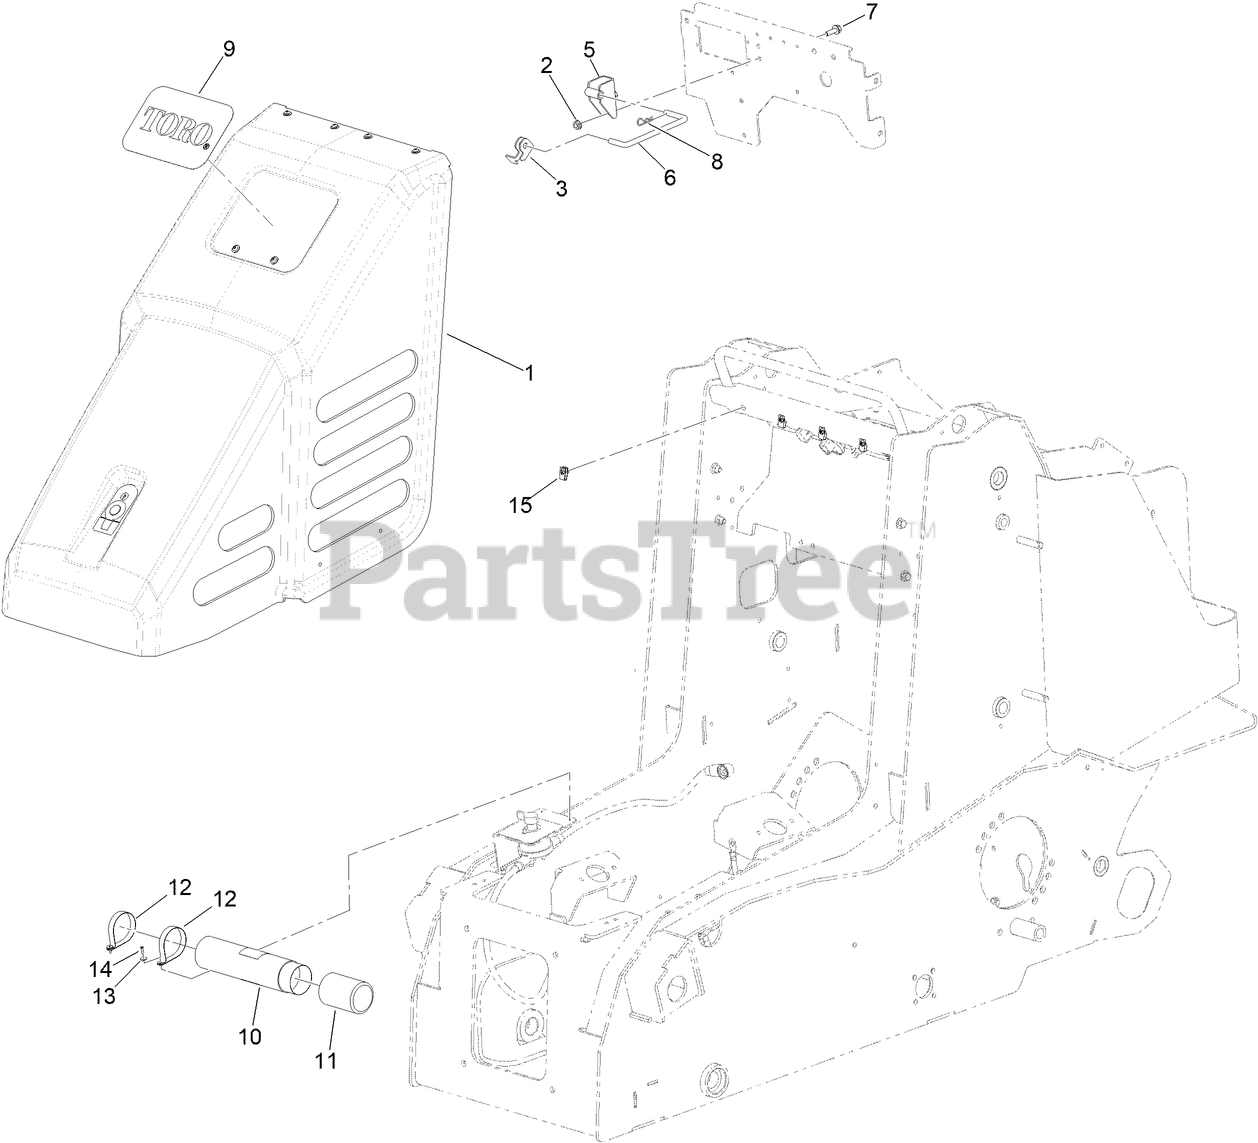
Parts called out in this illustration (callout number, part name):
1	HOOD ASM
2	NUT-HF
3	BRACKET-LATCH, LOCKING
5	BRACKET ASM, ROD
6	ROD-SUPPORT, HOOD
7	BOLT-CARR
8	PIN-COTTER
9	DECAL
10	TUBE-MANUAL
11	CAP-HOUSING
12	CLAMP-R
13	RIVET-POP
14	WASHER-BACK
